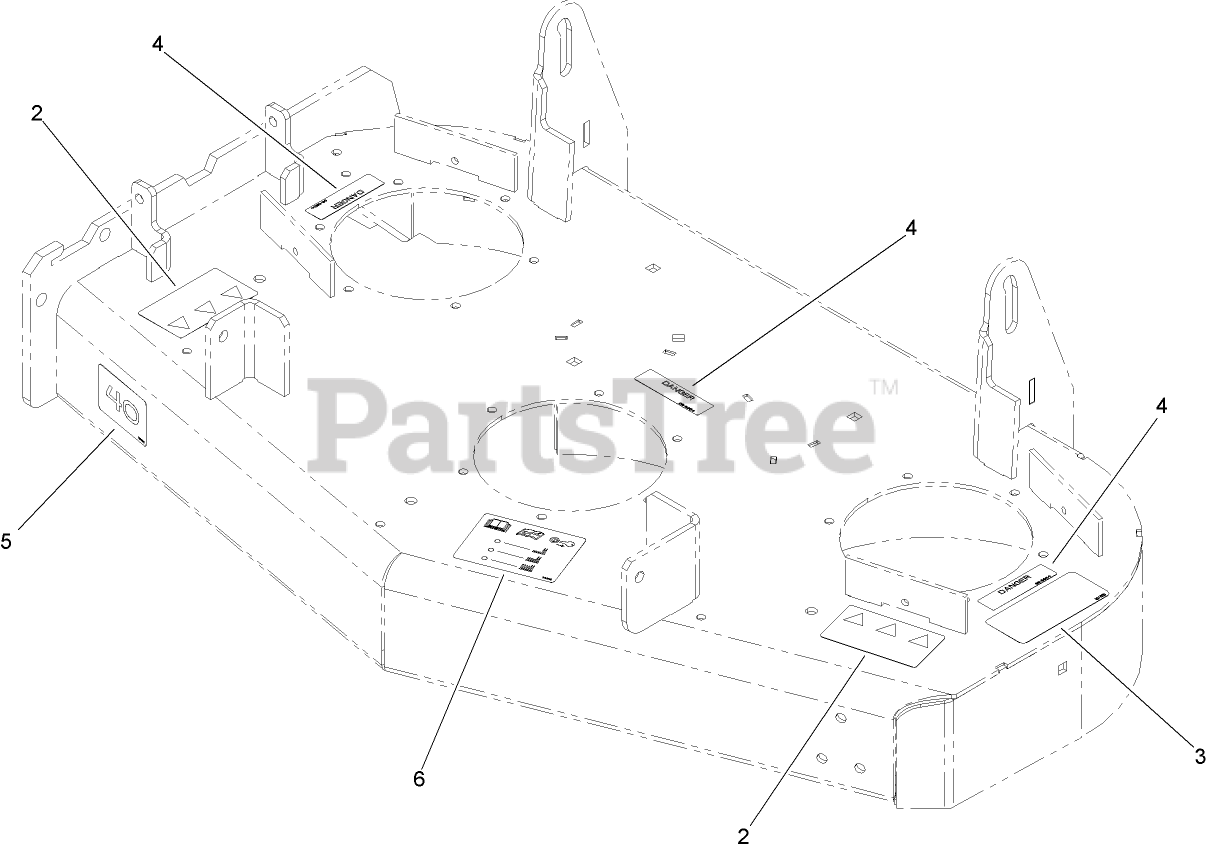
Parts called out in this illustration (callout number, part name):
2	DECAL-DANGER
3	DECAL-TORQUE, BLADE BOLT
4	DECAL-WARNING
6	DECAL-SCALP, ANTI
